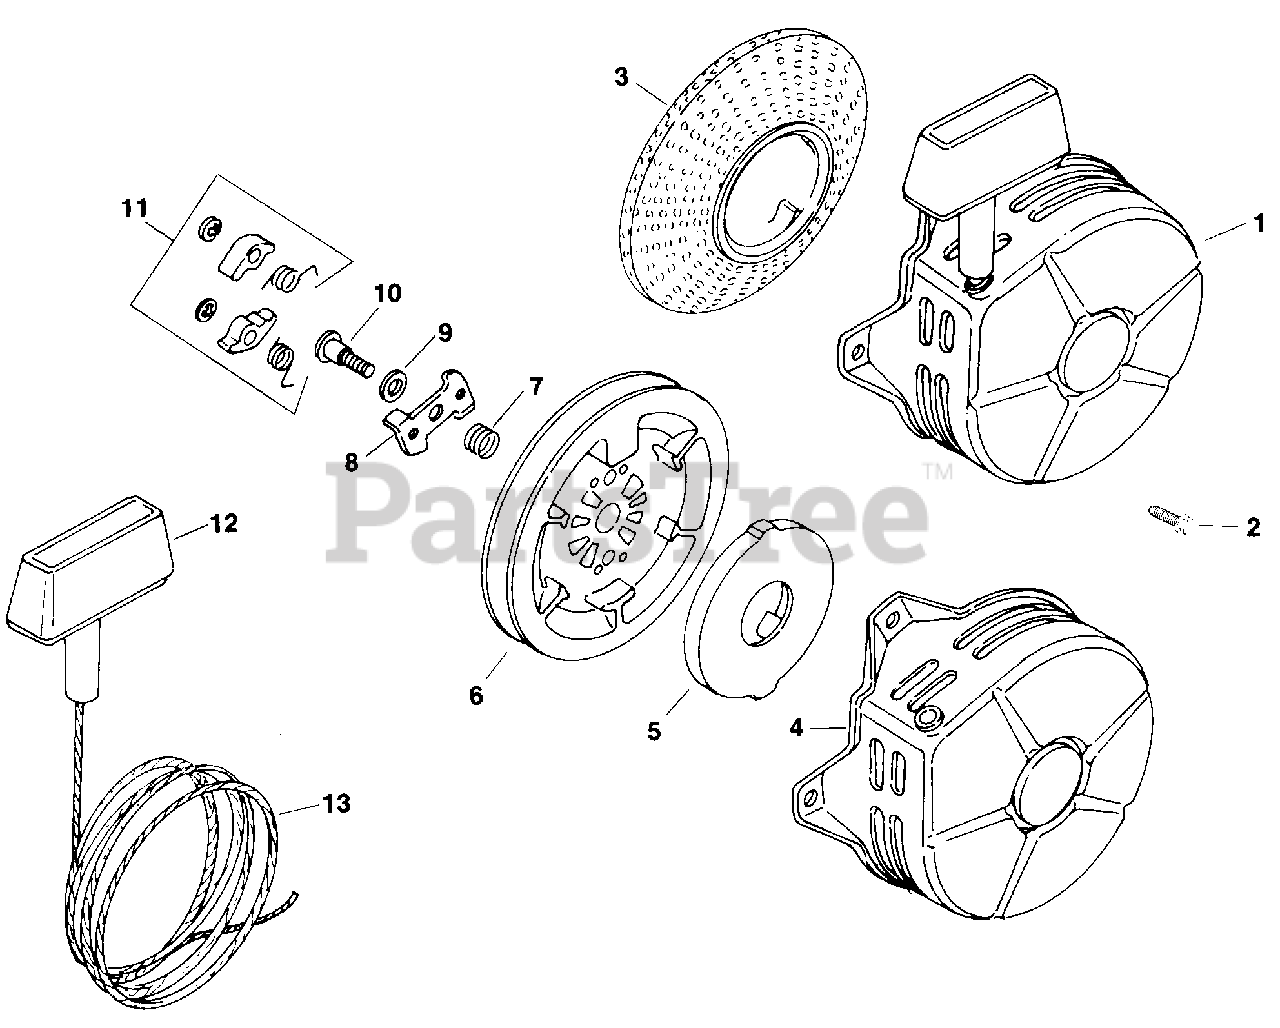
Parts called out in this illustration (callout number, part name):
1	Starter, Retractable Assembly (Includes 4-13)
2	Screw, F.H.M. 10-24 x 1/4
3	Cup, Drive w/Screen
5	Spring, Brake
7	Spring, Brake
10	Screw 12-28 x 13/16
11	Kit, Dog Repair
13	Rope, Starting
